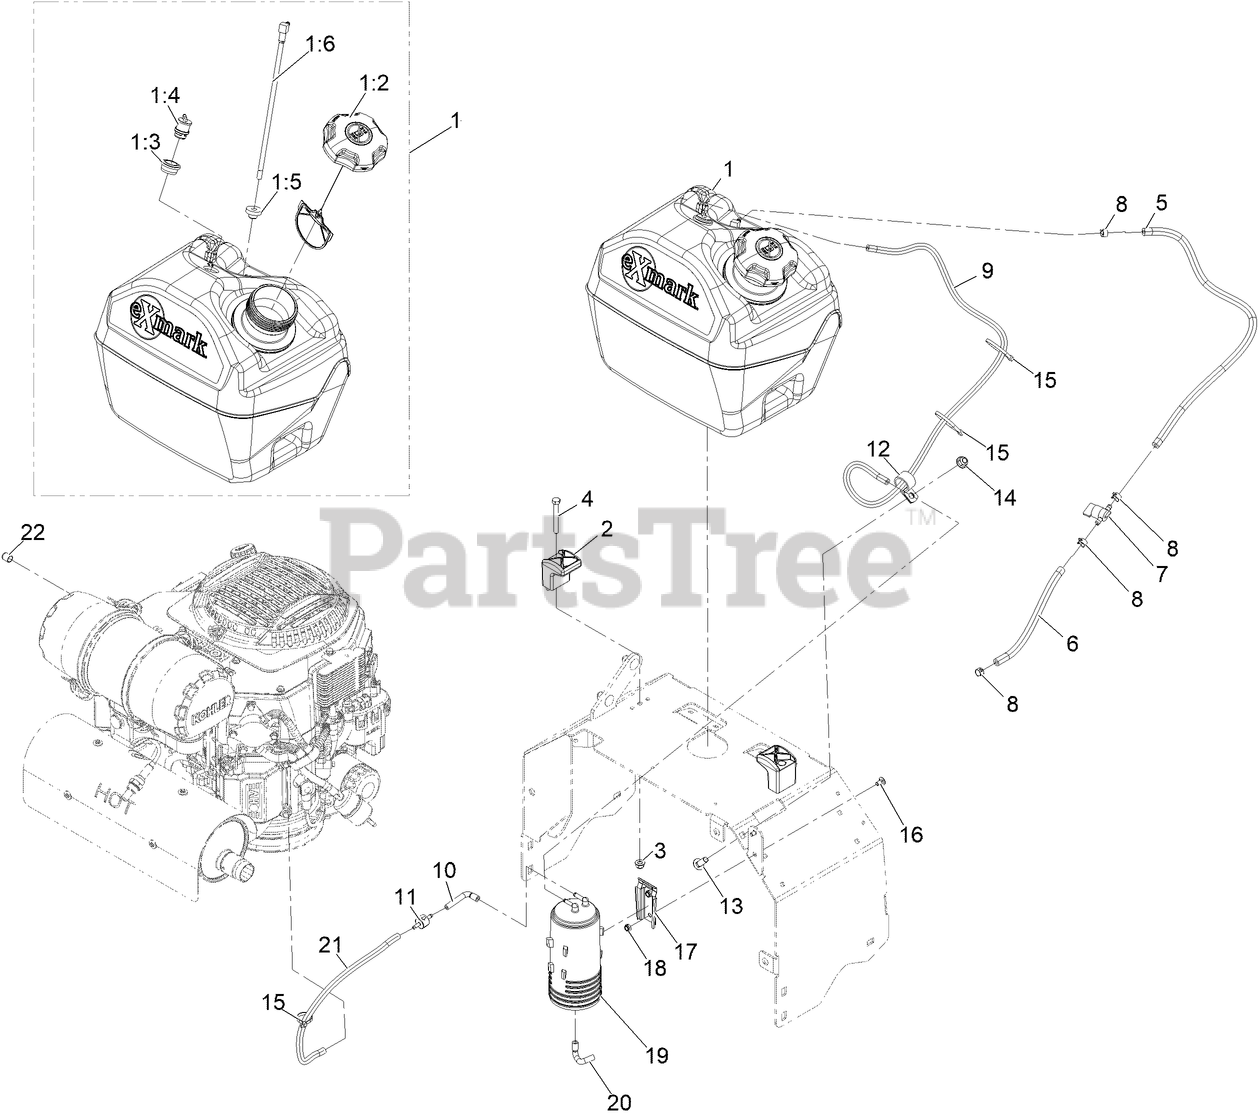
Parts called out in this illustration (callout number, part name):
1	ASM-Fuel Tank, 5 Gal, Exmark
1:2	CAP-FUEL, RATCHETING
1:3	GROMMET
1:4	VALVE-VENT, FUEL
1:5	BUSHING
1:6	FITTING, FUEL W/LINE AND SCREEN
2	CLAMP-TANK
3	NUT-HF, NI
4	SCREW-HH
5	HOSE-FUEL
6	HOSE-FUEL
7	VALVE-FUEL
8	CLAMP-HOSE
9	HOSE-FUEL
10	HOSE-VENT, FORMED
11	VALVE-CHECK, VACUUM
12	CLIP-LOOM
13	SCREW-CARR
14	NUT-HF, NI
15	TIE-CABLE
16	SCREW-CARR
17	BRACKET-CANISTER, CARBON
18	NUT-LOCK, NI
19	CANISTER-CARBON, 800CC
20	HOSE-VENT, FORMED
21	HOSE-FUEL
22	PLUG-PORT
